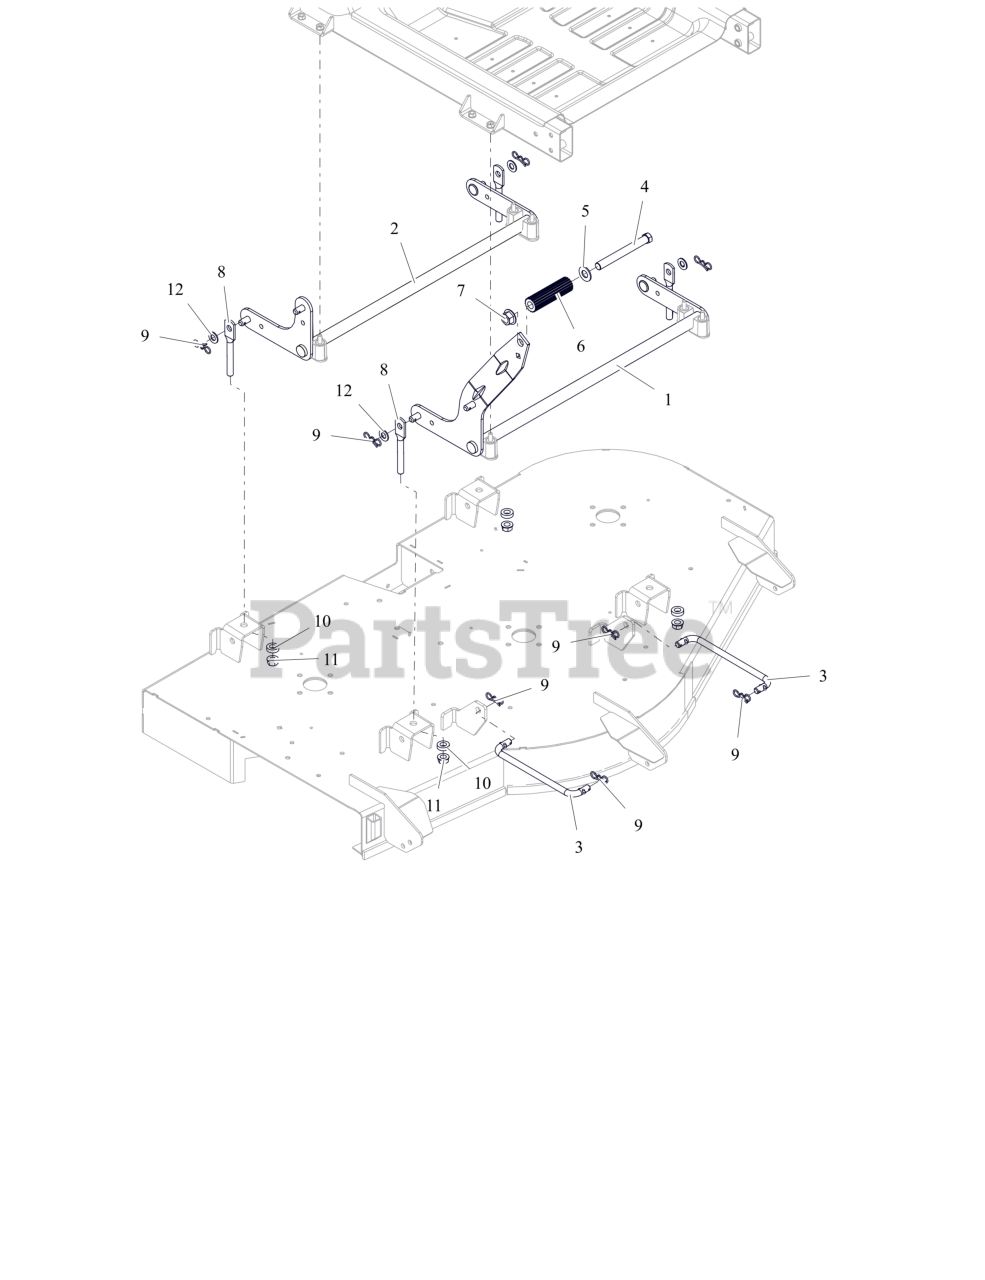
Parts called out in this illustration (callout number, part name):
1	WLDMT- FRONT LIFT PIVOT
2	WLDMT, REAR DECK PIVOT
3	LINK, DRAG
4	BLT, HEX .62-11X5.50 G5 FBP
5	WSHRFLT 5/8SAE CARBHARD FBP
6	ROD, FOOT PEDAL (BLACK)
7	NUT,FLG-TOP LK .625-11 FBP
8	LINK,DECK (HOLE-LONG)
9	PIN, BOWTIE .091X1.875 ZCC
10	WASHER, RUBBER
11	NUT-LK-CTR-FLG .500-13 GG ZCC
12	WSHR-FL-NYL .518X1.000X.080
